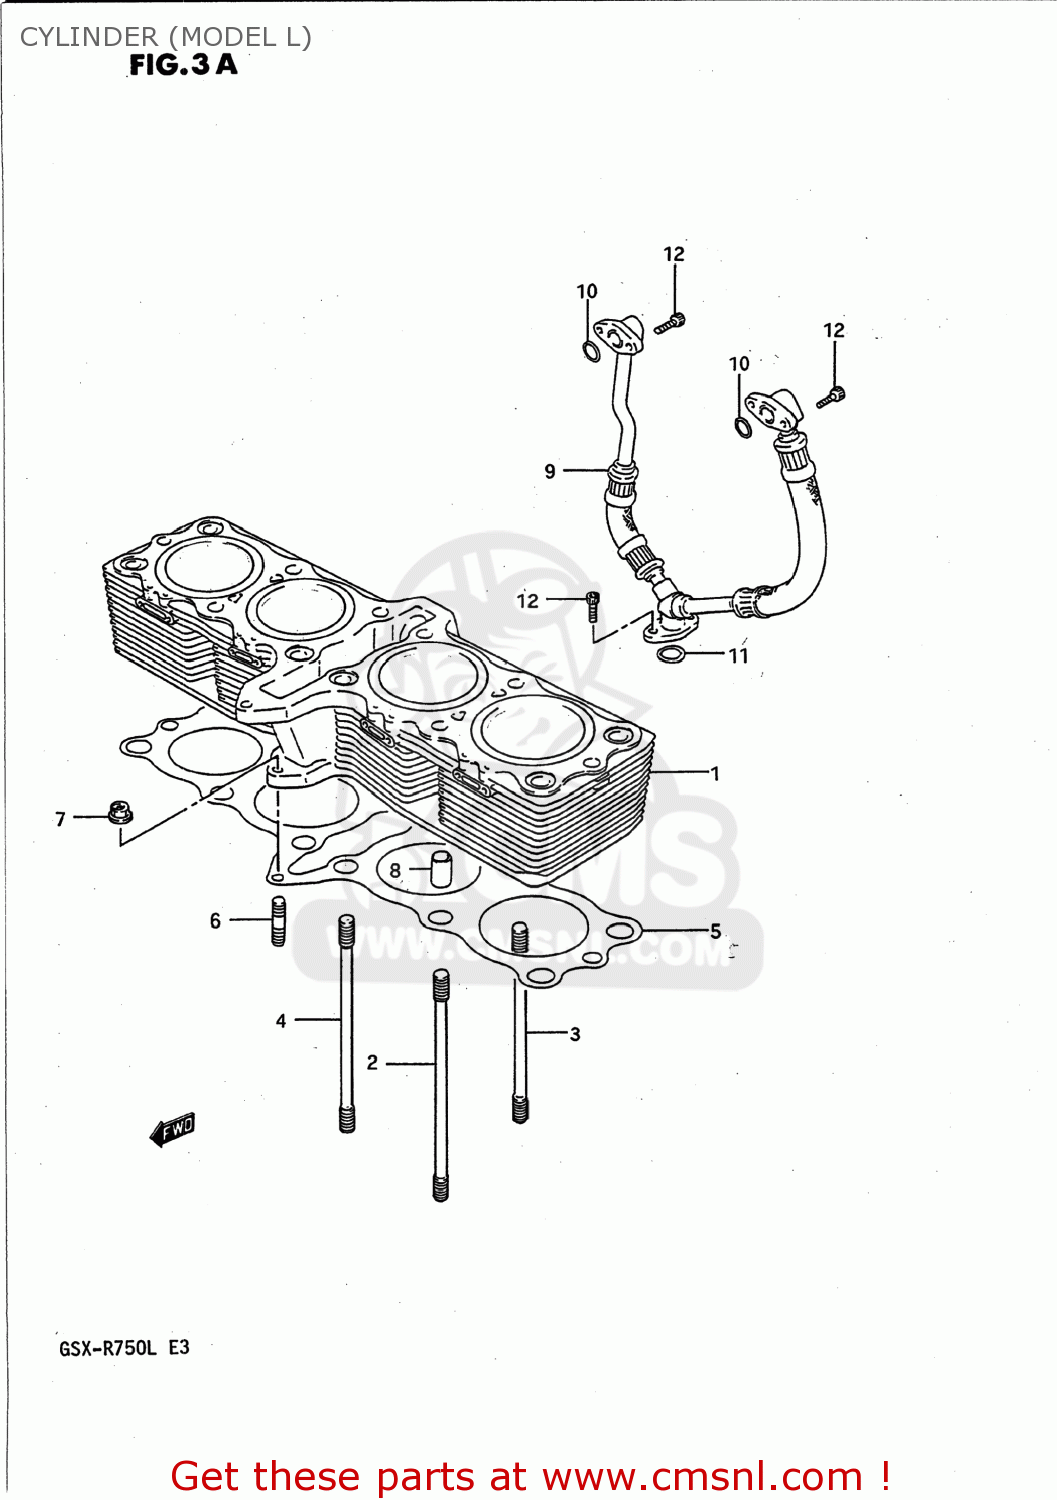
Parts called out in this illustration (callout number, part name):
1	CYLINDER
2	STUD BOLT (L:150)
3	BOLT,STUD
4	STUD
5	GASKET,CYLINDER (NAS)
6	STUD BOLT L:20
7	NUT 6MM
8	PIN
9	HOSE
10	O RING(D:2.5,ID:13.8)
11	O RING(D:2.4,ID:15.8)
12	BOLT
